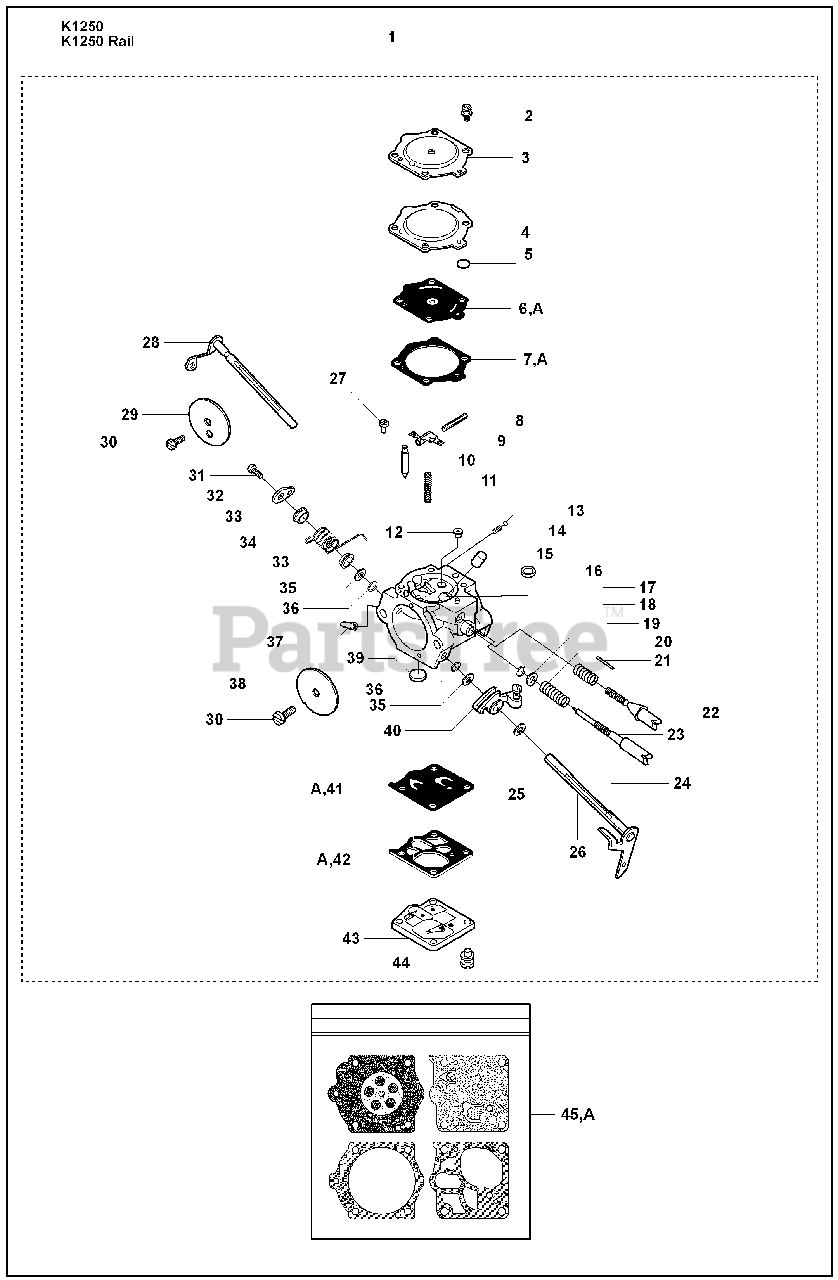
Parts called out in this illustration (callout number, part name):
1	CARBURETTOR
3	COVER-METERING DIAPH
6	DIAPHRAGM ASSY METER
7	GASKET-METERING DIAP
8	PIN-METERING LEVER
9	LEVER-METERING
10	VALVE INLET NEEDLE
11	SPRING-METER.LEVER
13	BALL-CHOKE FRICTION
14	SPRING-CHOKE FRICT.
15	NOZZLE ASSY
16	PLUG-WELCH
19	SPRING-NEEDLE
21	PIN THROTTLE STOP
22	SCREW IDLE SPEED
23	NEEDLE IDLE SPEED
26	SHAFT ASS'Y THROTTLE
27	SCREW-LEVER PIN
28	SHAFT ASS'Y
29	VALVE CHOKE
30	SCREW-VALVE
31	SCREW PAN HD
32	LEVER THROTTLE
33	BUSHING-THROTT.SPR.
34	SPRING THROTT RETURN
36	SEAL-THROTTLE SHAFT
37	FITTING FUEL INLET
38	VALVE THROTTLE
39	SCREEN-INLET
40	LEVER THROTTLE INNER
41	DIAPHRAGM-PUMP
42	GASKET-PUMP
43	COVER-PUMP
44	SCREW-PUMP COVER
45	GASKET KIT
